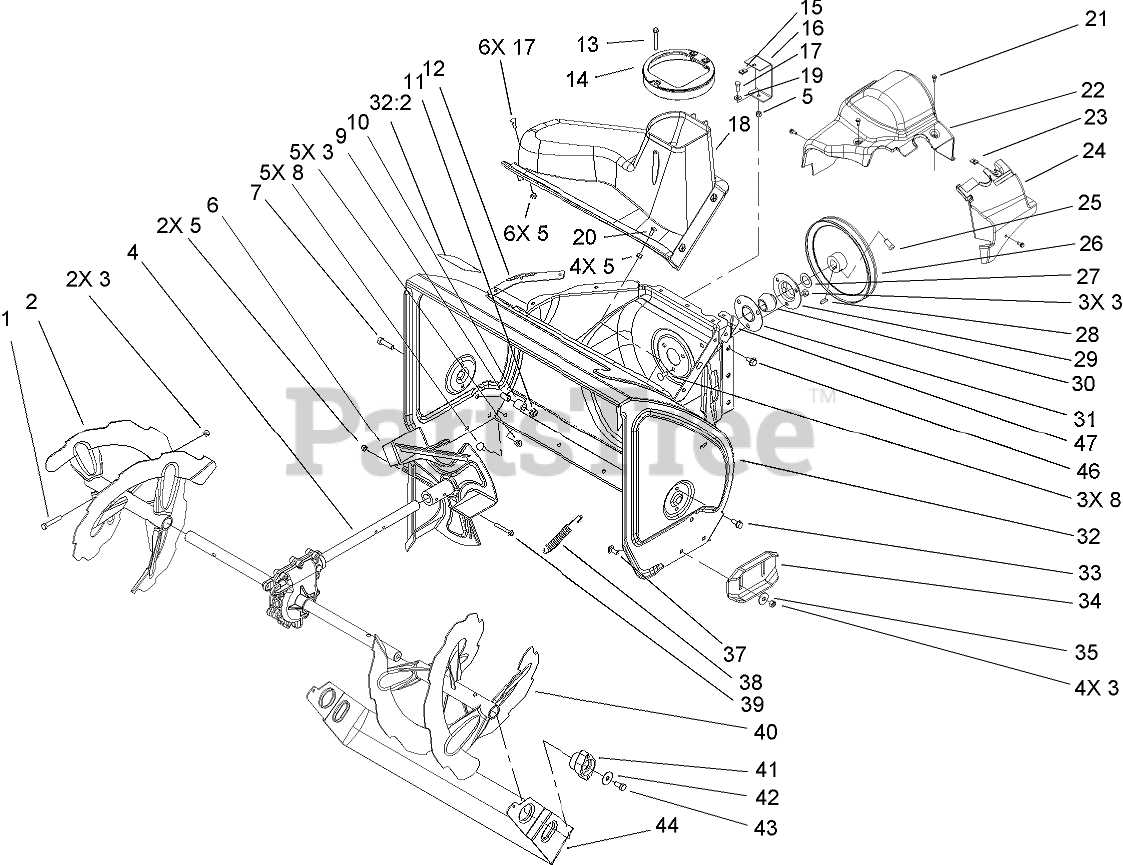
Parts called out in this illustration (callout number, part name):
1	SCREW-HH
2	RH AUGER ASM
3	NUT-LOCK, NI
4	AUGER GEARCASE ASM
5	NUT-LOCK, NI
6	IMPELLER ASM
7	SCREW-HH
8	SCREW-CARR
9	SPACER-SCRAPER, STOP
10	CUSHION-SCRAPER, STOP
11	NUT-HF
12	SEAL-FLANGE, COVER
13	SCREW-PLASTITE
14	GUIDE-CHUTE
15	NUT-SPEED, U-TYPE
16	BRACKET-COVER, CLIP NUT
17	SCREW-HH
19	WASHER-FLAT
20	BOLT-CARR
21	SCREW-HWH
22	COVER-BELT
23	NUT-SPEED
24	COVER-EXTENSION, BELT
25	SCREW-SET, SQH
26	PULLEY-IMPELLER
27	WASHER-THRUST
28	KEY-WOODRUFF
29	FLANGE-CUP, BEARING
30	BEARING-BALL
31	FLANGE-CUP, BEARING
32	HOUSING-AUGER, 28 INCH
32:2	DECAL-WARNING, AUGER
33	SCREW-HWHTF
35	WASHER
37	SCREW-CARR
38	SPRING-SCRAPER
39	SCREW-HHF
40	LH AUGER ASM
41	BEARING-AUGER
42	WASHER
43	SCREW-HH
44	SCRAPER-PIVOTING, 28 INCH
46	SCREW-HWHTF
